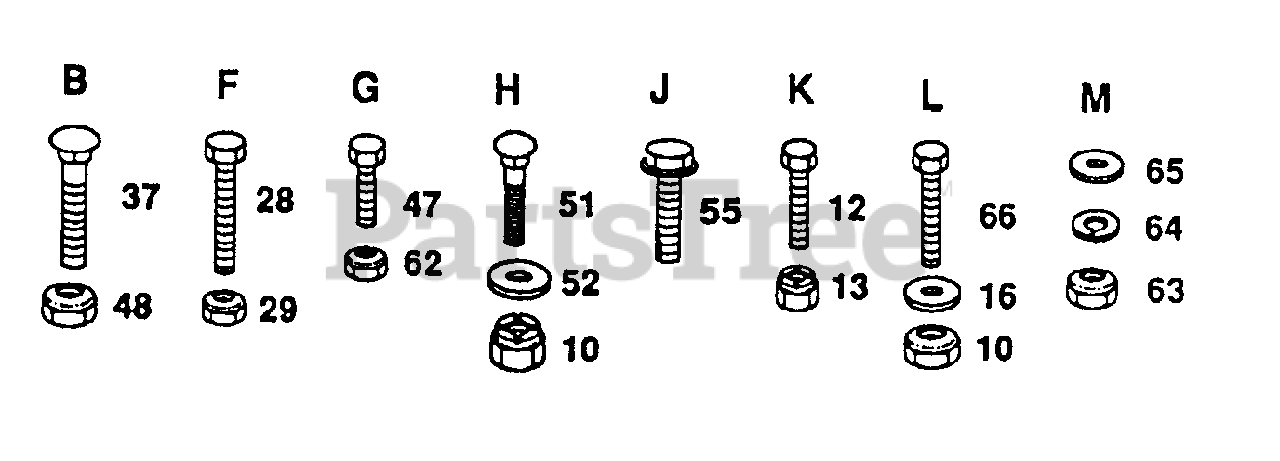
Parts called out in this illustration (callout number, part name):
10	Nut, Lock, 5/16-18
12	Bolt, Hex, 1/4-20 x 1/2
13	Nut, Lock 1/4-20
16	Washer, 11/32 x 3/4 x 16 Ga.
28	Bolt, Shoulder
29	Nut, Hex Flange 1/4-20
37	Bolt, Hex 3/8-16 x 1
47	Bolt, Carriage 3/8-16 x 3/4
48	Nut, Lock, 3/8-16
51	Bolt,Carriage, 5/16-18 x 1
52	Washer, 11/32 x 1 x 10 Ga.
55	Screw, Hex Wsh Thdrol. 3/8-16 x 1/2
62	Nut,Centerlock 3/8-16
63	Nut,Hex 1/4-20
64	Washer, Lock 1/4
65	Washer, 9/32 x 3/4 x 16 Ga.
66	Bolt, Hex 5/16-18 x 3/4
